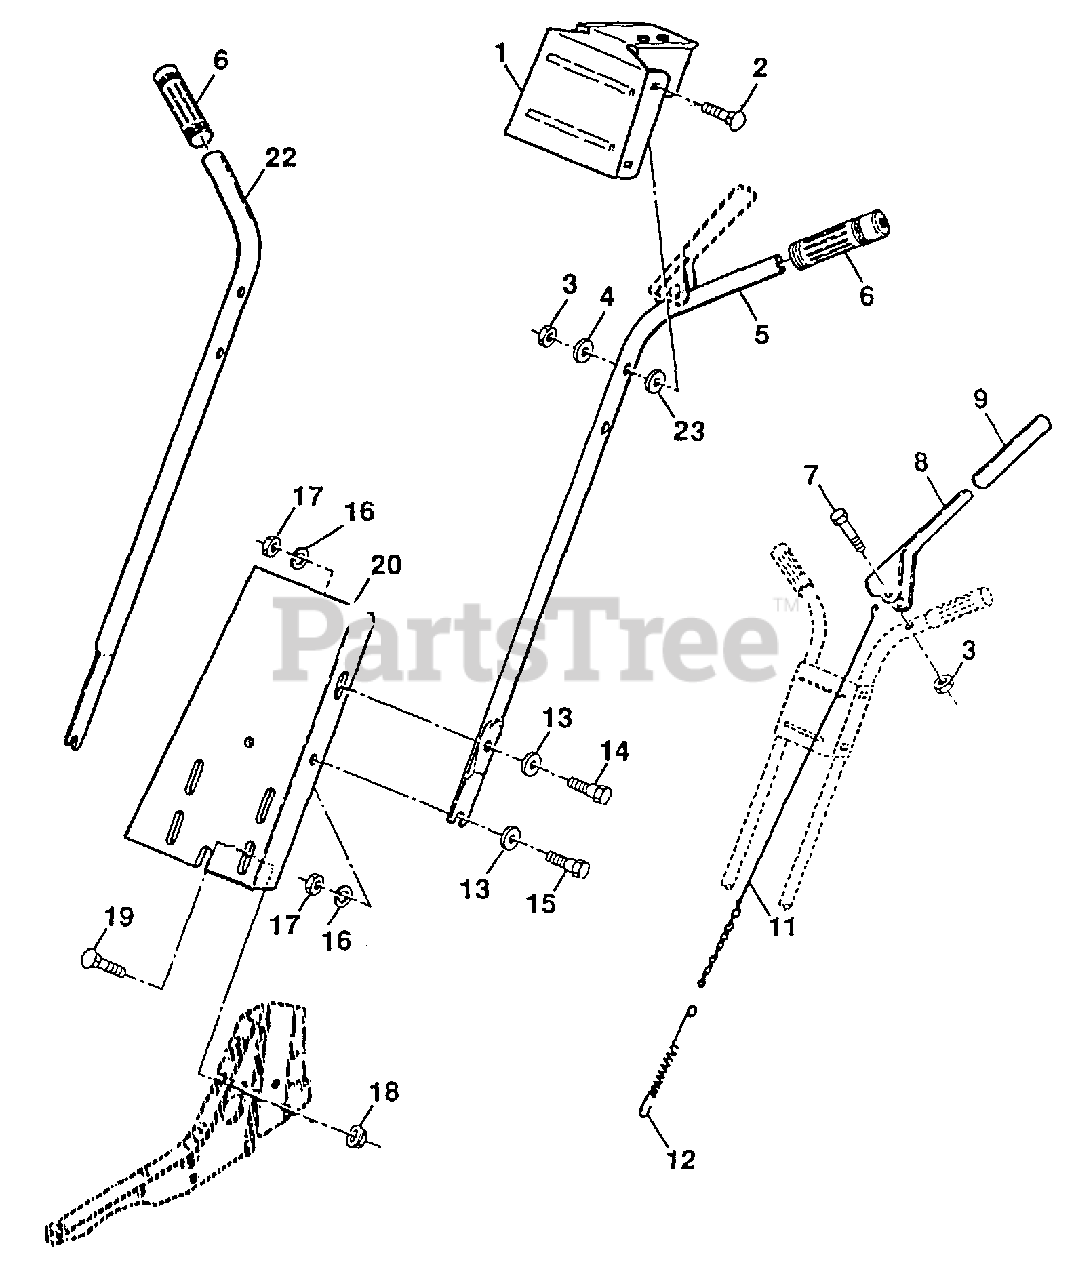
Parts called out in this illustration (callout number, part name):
1	Bracket, Handle
2	Bolt, Carriage 5/16-18 UNC x 1-1/2
3	Locknut, Crown 5/16-18
4	Washer 11/32 x 11/16 x 16 Ga.
5	Handle, L.H.
6	Grip, Handle (AYP part number)
7	Bolt, Hex 5/16-18 x 1-1/2
8	Lever, Control, Tine
9	Grip, Lever
11	Cable, Control, Tine (AYP part number)
12	Spring, Extension
13	Washer 3/8 x 7/8 x 14 Ga.
14	Bolt, Hex Hd 5/16-18 x 1 (AYP part number)
15	Bolt, Hex Hd 5/16-18 x 3/4
16	Washer, Lock 5/16
17	Nut, Hex 5/16-18
18	Nut, Flanged 5/16-18 (AYP part number)
19	Bolt, Carriage 5/16-18 x 3/4 Gr. 5
20	Panel, Handle
22	Handle, R.H.
23	Washer 13/32 x 13/16 x 12 Ga.
